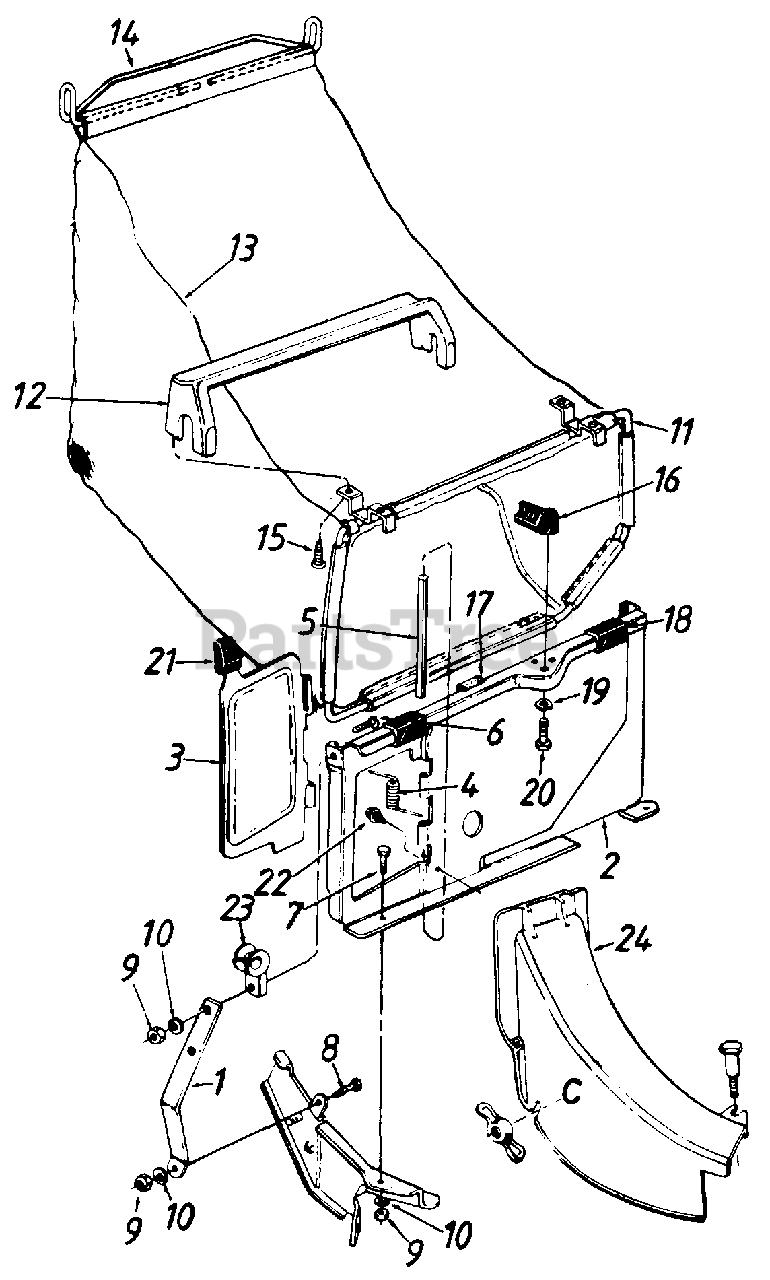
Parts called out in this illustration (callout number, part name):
1	Panel Support Brkt.
2	Top Catcher Panel Ass'y.
3	Top Discharge Door
4	Torsion Spring
5	Pivot Pin
6	Truss Mach. Scr. 1/4-20 x .75" Lg.
7	Hex Bolt 1/4-20 x .50n Lg.
8	Hex Bolt 1/4-20 x .62n Lg.'
9	Hex Nut 1/4-20 Thd.
10	L-Wash. 1/4" l.D.
11	Front Grass Catcher Frame
12	Grass Catcher Handle
13	Grass Bag
14	Upper Bag Handle
15	Hex AB-Tap Scr. #12 x 1.0"
16	Grass Catcher Locking Knob
17	Foam Strip l" Lg.
18	Panel Clip
19	Spring Wash. 32" l.D.
20	Hex Bolt 1/4-20 x .62 Lg.
21	Door Grip
22	Hex B-Tap Scr. #10 x .38
23	Rope Guide
24	Top Discharge Chute Ass'y.
